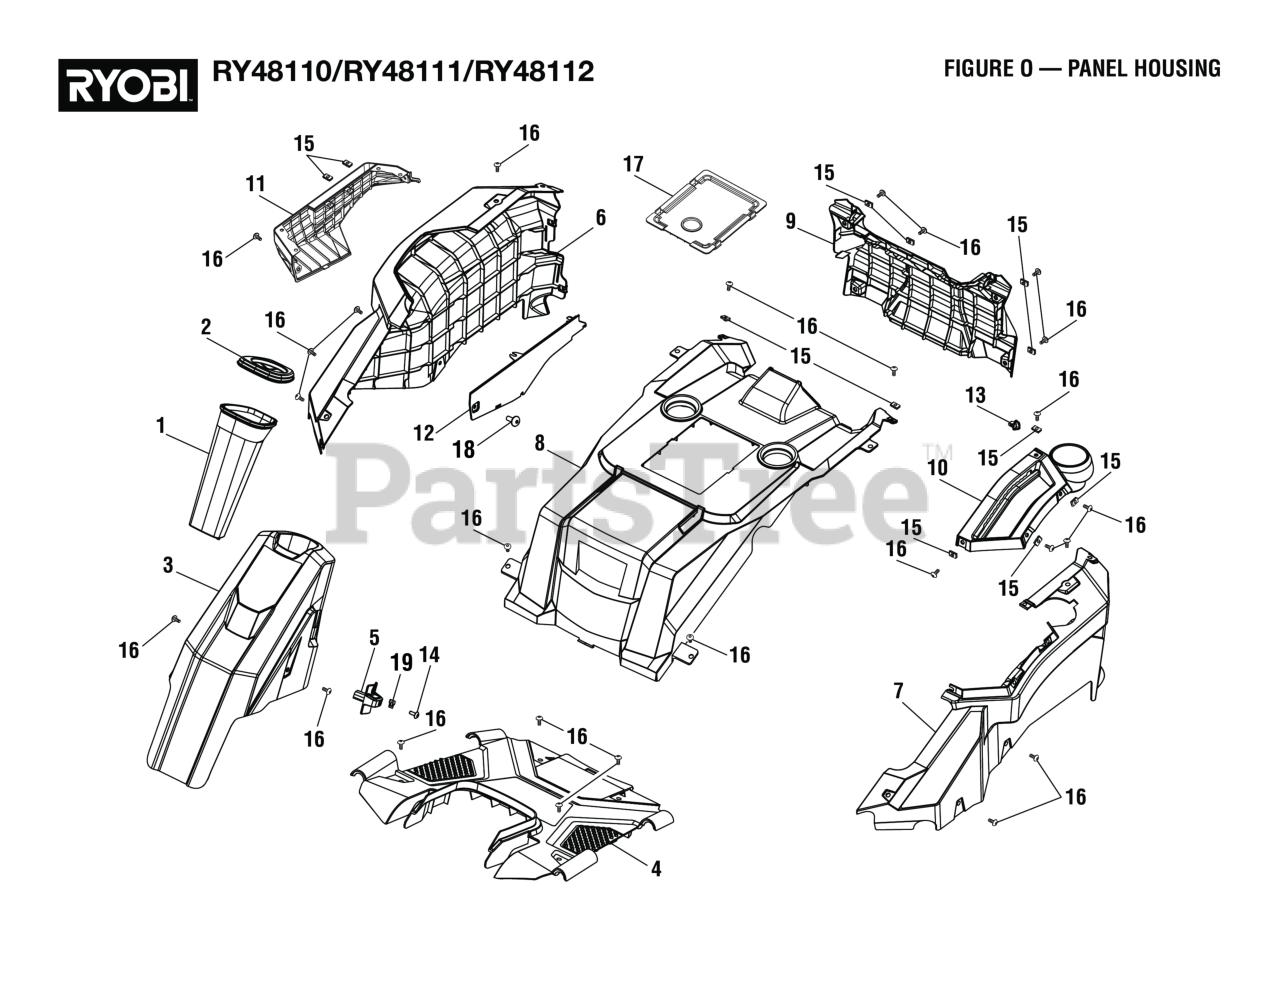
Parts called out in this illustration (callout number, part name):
1	Upper Steering Column
2	Steering Column Cover
3	Lower Steering Column
4	Floor Pan
5	Parking Brake Lever
6	Right Fender Housing
7	Left Fender Housing
9	Rear Mover Cover
10	Deck Lift Console
12	Rear Console Cover
13	Indicator Flag
14	Screw (M4 x 10 mm, Pan Hd.)
15	Clip-On Nut (M6)
16	Screw (M6 x 10 mm, Soc. Button Hd.)
17	Battery Access Cap
18	Screw (ST4.2 x 13 mm)
19	Adjusting Washer
